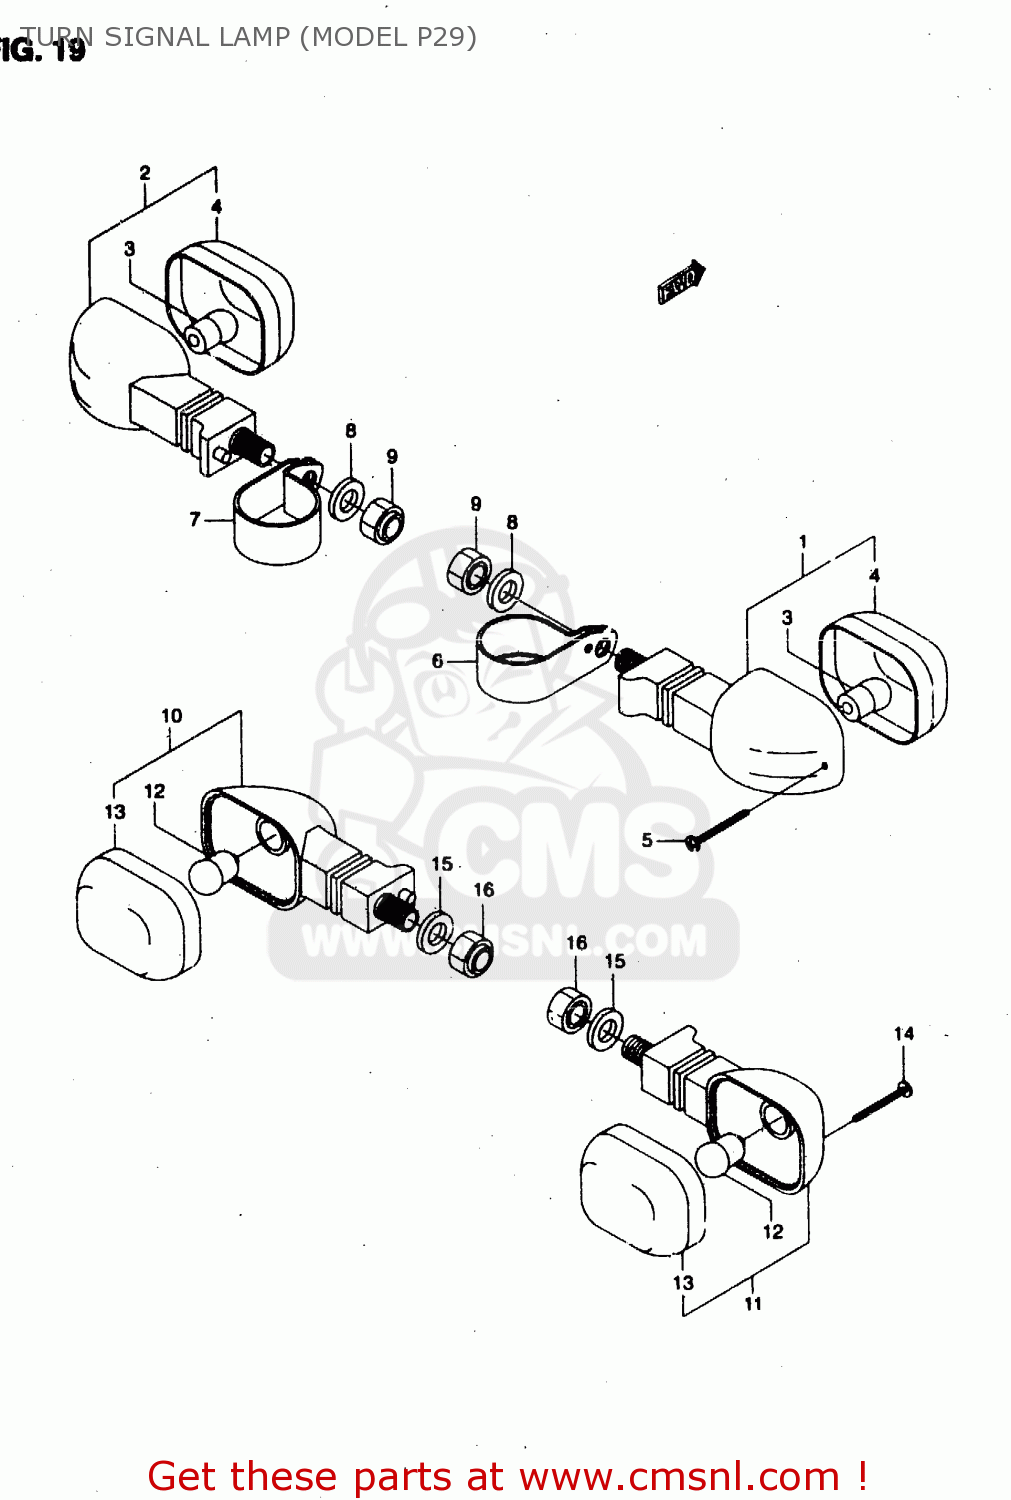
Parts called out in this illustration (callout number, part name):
1	LAMP ASSY,FRON
2	LAMP ASSY, FRO
3	BULB(12V10W)
4	LENS
5	TAPPING SCREW
6	CLAMP, FRONT TURSGNAL RH
7	CLAMP, FRONT TURSGNAL LH
8	WASHER
9	NUT
10	FLASHER
11	TURNSIGNAL,FR
12	BULB(12V10W)
13	LENS
14	TAPPING SCREW
15	WASHER
16	NUT
